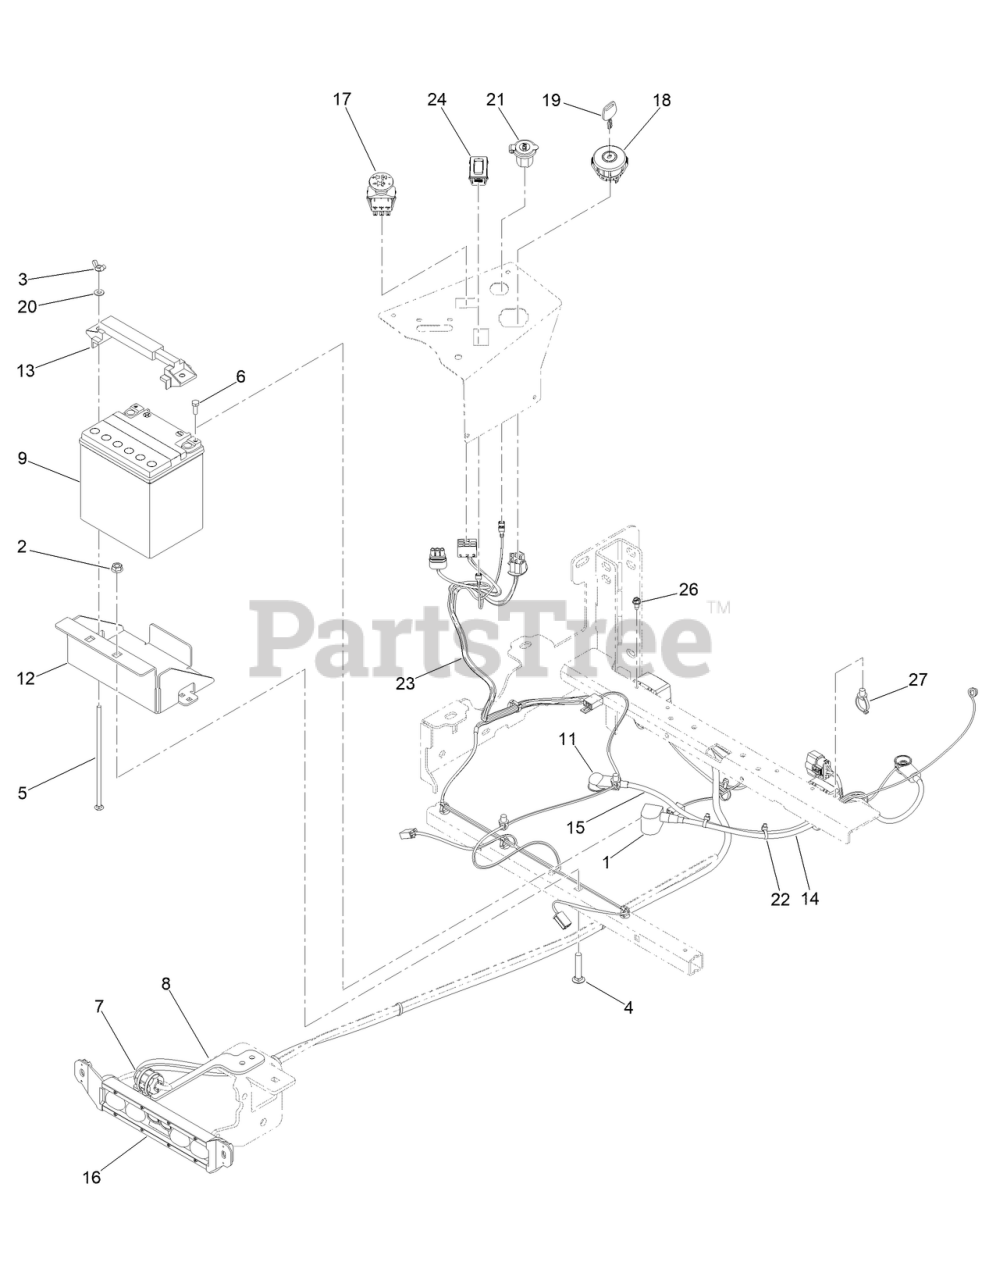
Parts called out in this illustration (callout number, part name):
1	INSULATOR-BATTERY
2	3/8-16 HEX FLANGE NUT W/SERR ZINC YELLOW
3	NUT-WING
4	SCREW-CARR
5	1/4IN-20X8IN GR5 CARRIAGE BOLT
6	SCREW-HH
7	FAIR-RITE ROUND CABLE SNAP-IT SIZE B
8	FAIR-RITE BRACKET PAINTED
9	BATTERY - ETX30LA - 400CCA
11	STRAIGHT INSULATING TERMINAL COVER
12	MWR BATTERY BOX
13	BATTERY HOLD DOWN
14	MWR POSITIVE BATTERY CABLE 25IN
15	MWR NEGATIVE CABLE 28
16	FULL BEAM WITH LIGHTED HELMET LIGHT BAR
17	PTO SWITCH
18	IGNITION SWITCH
19	2023 MWR KEY
20	WASHER-FLAT
21	12 VOLT AUXILLIARY PLUG
22	TIE-CABLE
23	HARNESS-WIRE
24	HOUR METER
26	SCREW-HWH
27	CLIP-TIE
